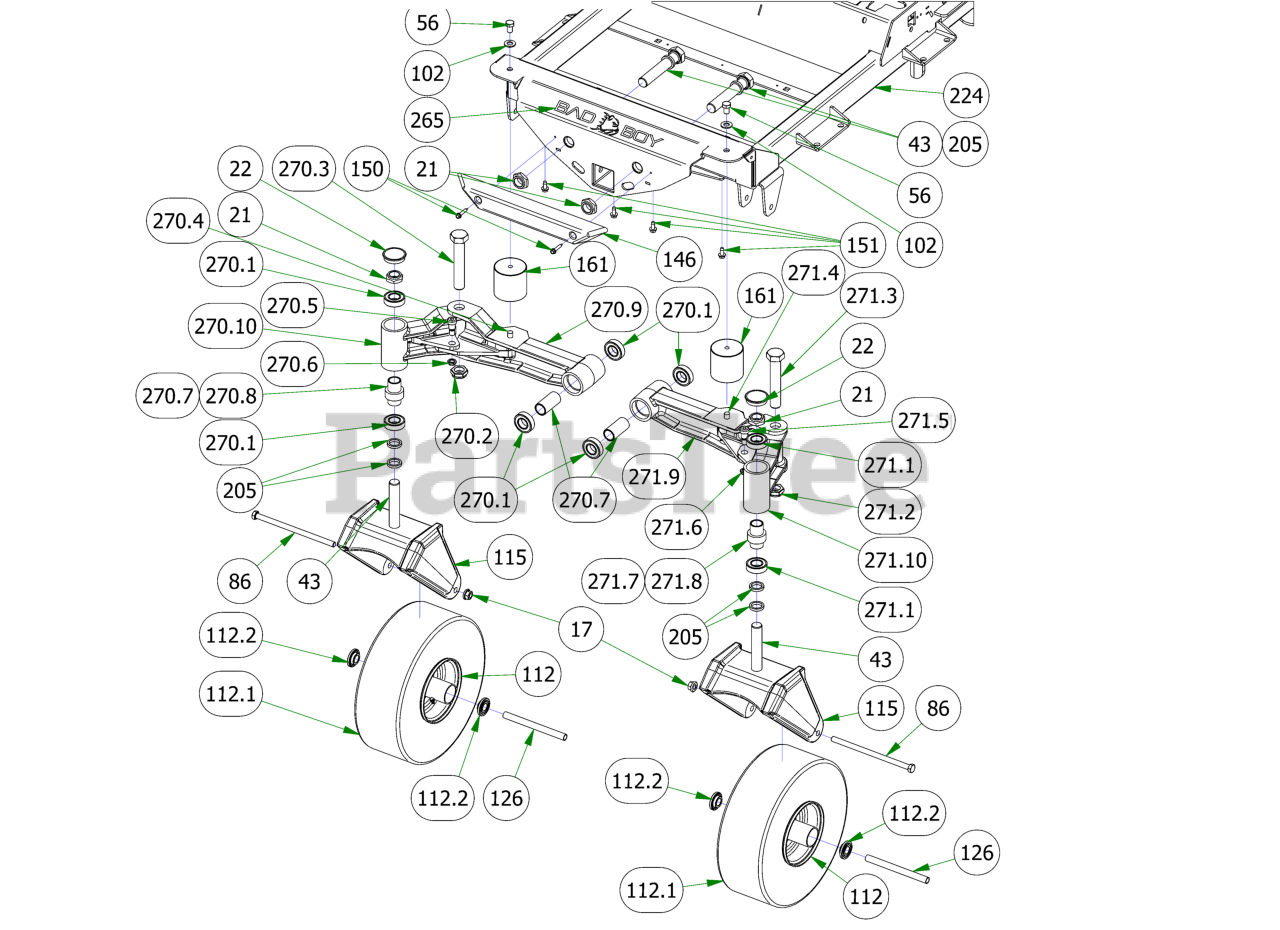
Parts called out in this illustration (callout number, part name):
17	1/2-13 NYLON INSERT FLANGE LOCKNUT ZINC
21	1"-14 NYLON INSERT JAM LOCKNUT ZINC
22	2017 Bearing Cover
43	1"-14 X 5-1/2 HEX CAP SCREW (GR.8) ZINC YELLOW
56	1/2-13 X 3/4 HEX CAP SCREW (GR.5) ZINC
86	1/2-13 X 9 HEX CAP SCREW (GR.5) ZINC
102	1/2 SAE FLAT WASHER (1-1/16" OD) GR.8 ZINC YELLOW
112	2019 15x6.00-6 Non Pneumatic Black Front Assembly
112.1	15x6-6 Tire Only
112.2	1-3/4" Bearing-Large Bore Front Rim
115	2020 R Series Cast Front Fork
126	Front Wheel Spanner
146	2017 XP Bumper
150	1/4-14 X 1-1/2 HEX WASHER UNSLOT TEK/3 ZINC
151	5/16-18 X 3/4 HEX WASHER SLOT (F) TCS ZINC
161	Vibration Mount-Blue Dot
205	1.02 ID X 1.38 OD X .250 THK SPACER ZINC
224	2019 Renegade Gas Frame - Powdercoated
265	Flying Bulldog Front Bumper Decal
267	Independetly Articulating Front Suspension Arms Patent Decal
270	2022 61/72 Rogue/Renegade Front Suspension Asy RH
270.1	1641 BEARING W/2 CONTACT RUBBER SEALS
270.2	1" Fine Thread 1/2 Nylock Nut
270.3	1"-14 X 5-1/2 HEX CAP SCREW (GR.8) ZINC YELLOW
270.4	1/2-13 x 1" Stud
270.5	5/8 X 5/8 SOCKET SHOULDER BOLT ZINC YELLOW
270.6	1/2-13 NYLON INSERT JAM LOCKNUT ZINC
270.7	2016 Front Bearing Spacer
270.8	Rubber Stabilizer (Front Forks) [R series]
270.9	61" & 72" Rogue Front Suspension Arm Inner RH
270.10	61" & 72" Rogue Front Suspension Arm Outer RH
271	2022 61/72 Rogue/Renegade Front Suspension Asy LH
271.1	1641 BEARING W/2 CONTACT RUBBER SEALS
271.2	1" Fine Thread 1/2 Nylock Nut
271.3	1"-14 X 5-1/2 HEX CAP SCREW (GR.8) ZINC YELLOW
271.4	1/2-13 x 1" Stud
271.5	5/8 X 5/8 SOCKET SHOULDER BOLT ZINC YELLOW
271.6	1/2-13 NYLON INSERT JAM LOCKNUT ZINC
271.7	2016 Front Bearing Spacer
271.8	Rubber Stabilizer (Front Forks) [R series]
271.9	61" & 72" Rogue Front Suspension Arm Inner LH
271.10	61" & 72" Rogue Front Suspension Arm Outer RH
